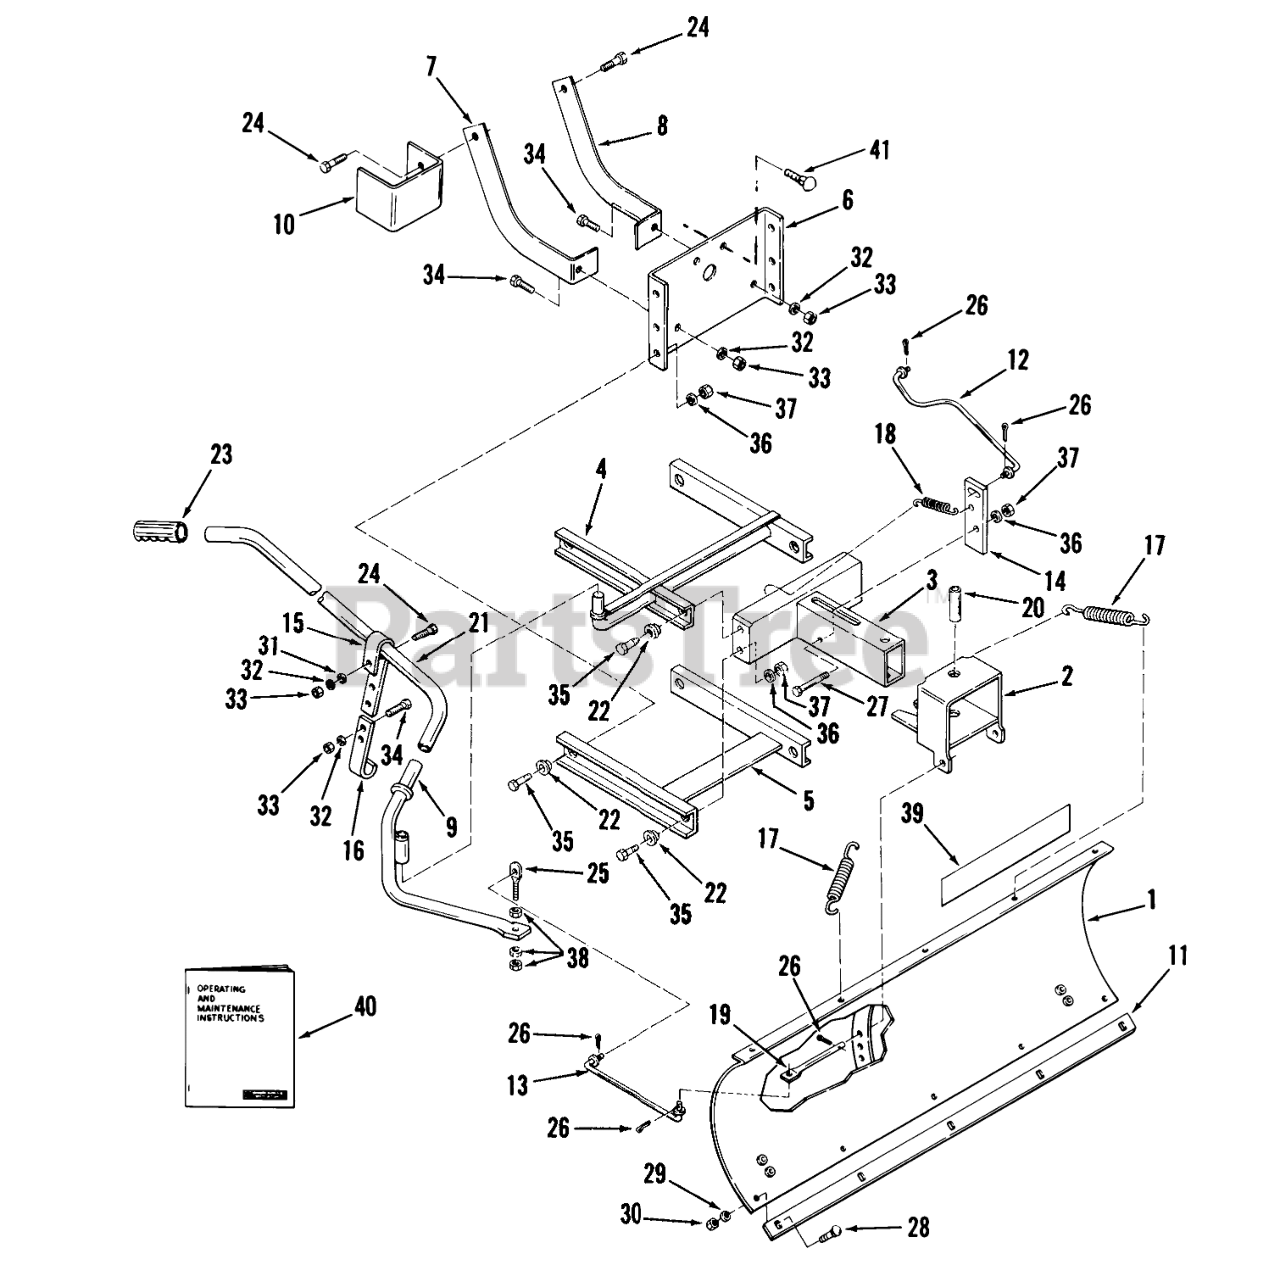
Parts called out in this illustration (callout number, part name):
1	Blade
2	Quadrant
3	Frame
4	Upper Parallel Bar
5	Lower Parallel Bar
6	Frame Mount
7	R.H. Frame Mount Brace
8	L.H. Frame Mount Brace
9	Lower Handle
10	Latch Bracket
11	Blade Edge
12	LINK INDEX
13	Pivot Link
14	Index Bar
15	Upper Latch
16	Lower Latch
17	Trip Spring
18	SPRING-TENSION
19	PIN-QUADRANT
20	ROD-QUADRANT
21	Extension Handle
22	SPACER-PAR BAR
23	GRIP-HANDLE BAR
24	Bolt
25	Eye Bolt
27	Bolt
28	Bolt-Carriage
29	Washer
30	Nut
31	WASHER 5/16 SAE
32	Lockwasher
33	Nut
34	Bolt
35	BOLT
36	LOCKWASHER
37	Nut
38	Nut
39	Decal-Rear
40	Operating and Maintenance Instructions
41	Bolt-Carriage
